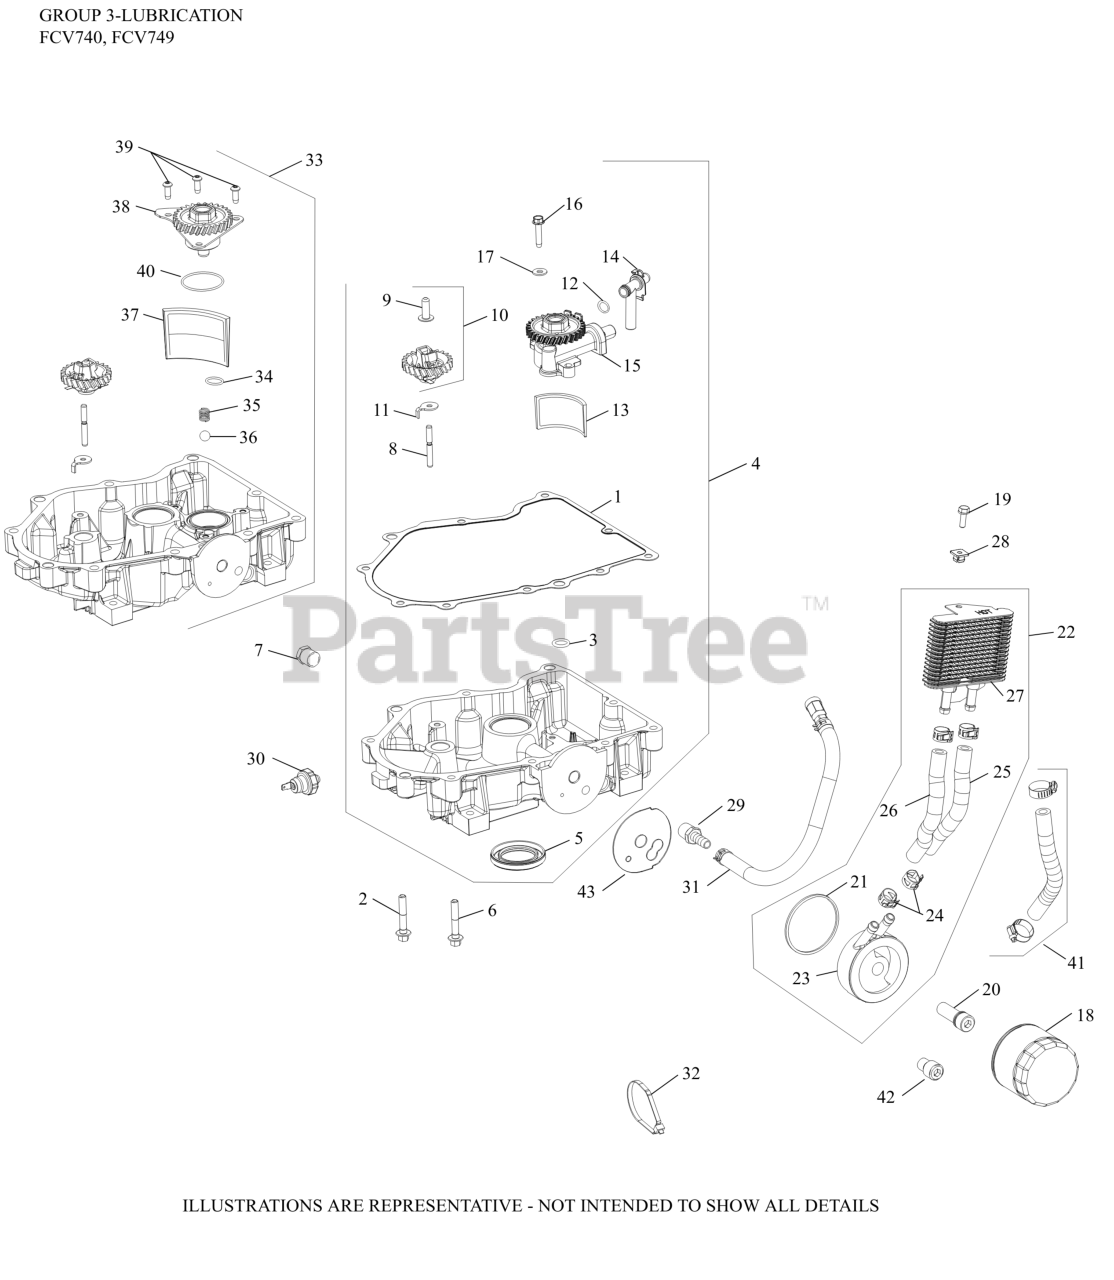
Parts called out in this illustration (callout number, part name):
1	GASKET, OIL PAN
2	SCREW, FLG M8X1.25X45
6	SCREW, HEX FLANGE
7	PLUG, HD PIPE 3/8"
8	SHAFT, GOVERNOR GEAR
9	PIN, GOVERNOR REGULATING
10	KIT, GOVERNOR GEAR W/PIN
11	TAB, LOCKING
18	OIL FILTER
19	SCREW, TAP M6X1.7X18
21	O-RING, OIL COOLER
22	COOLER, OIL & DIVERTER ASSEMBLY
23	ADAPTER, OIL FILTER (CV EFI)
24	CLAMP, HOSE LOW PROFILE
24	CLAMP, HOSE (KM)-USE 25 237 31-S
28	NUT, PLASTIC - BLACK
29	FITTING, BARBED
30	SENSOR, OIL PSI
31	HOSE, OIL ASSEMBLY-(#25326116S)
33	KIT, OIL PAN ASSEMBLY
33	PAN, ASSEMBLY OIL (SERVICE)
35	SPRING, COMPRESSION
36	PRESSURE RELIEF BALL
37	SCREEN, OIL
38	PUMP, OIL ASSEMBLY
39	SCREW, BUTTON HEAD
40	O-RING (1.78" DIA)
41	KIT, HOSE 140MM
NI	NIPPLE, OIL FILTER
